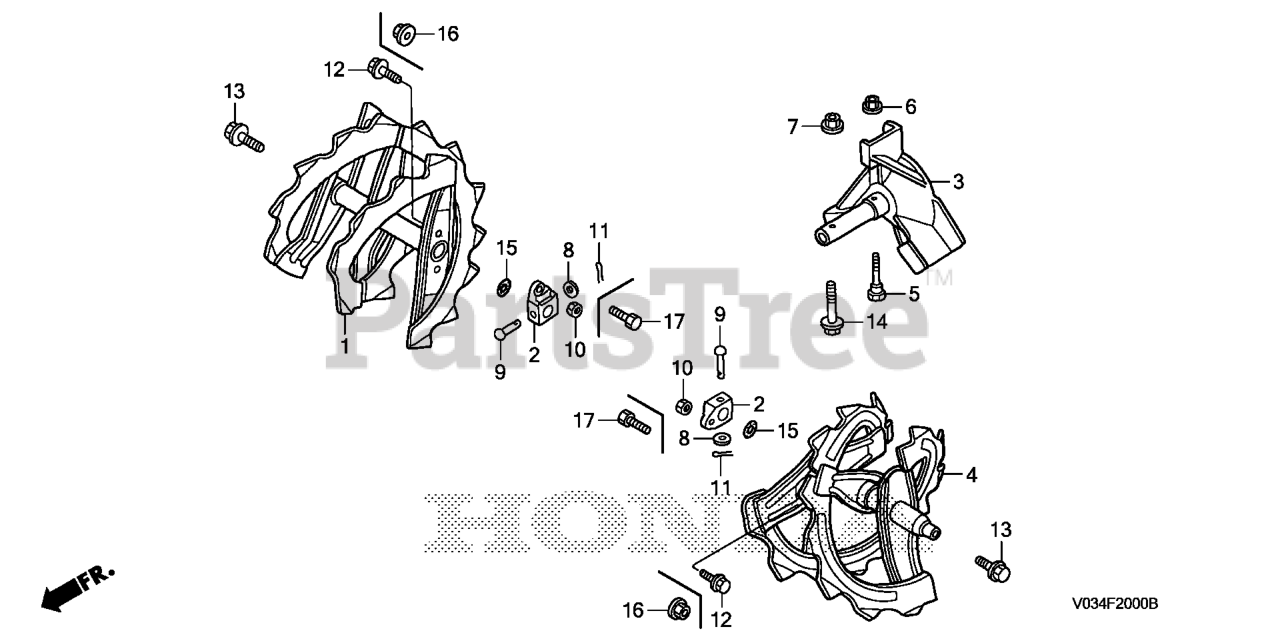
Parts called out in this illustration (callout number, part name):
2	BOSS, LOCK BOLT
5	BOLT, LOCK
6	NUT, SELF-LOCK (6MM)
7	NUT, FLANGE (8MM)
8	WASHER, PLAIN (7MM)
9	PIN (7X40)
10	NUT, HEX. (6MM)
11	PIN, SPLIT (3.0X25)
11	PIN, COTTER (3.0X45)
12	BOLT, FLANGE (6X16) Use from Engine SN 2056820.
13	BOLT, FLANGE (8X16) Use from Engine SN 1000016.
14	BOLT, FLANGE (8X35)
15	O-RING (19.8X1.9) (ARAI)
16	NUT, SELF-LOCK (6MM)
17	BOLT, HEX. (6X16)
